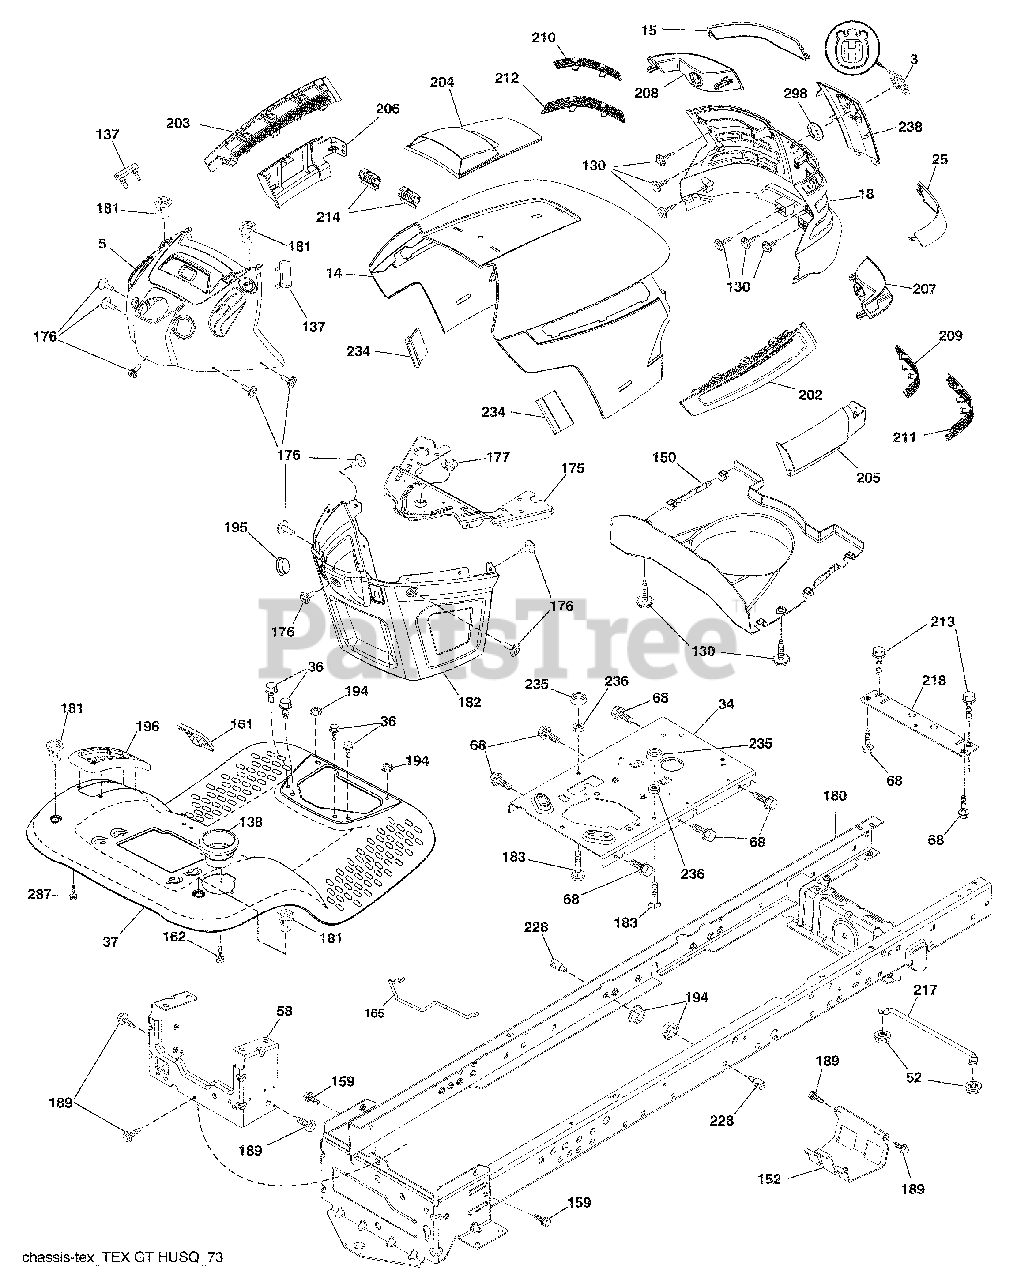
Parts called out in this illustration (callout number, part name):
3	Logo
14	Hood
18	Grille/Lens Asm.
34	Plate Engine
36	Screw 5/16-18 x 3/4
52	Nut Lock 5/16-18
58	Drawbar Upper 2PC Sml. Fender
68	Screw Thdrol 5/16-18 x 1/2
130	Screw #10 x 0.750
137	Bumper Dash
138	Cupholder
152	Shield Browning
159	Screw Hexwsh Thrd 3/8-16 x 3/4
161	Window Fuel
165	Support Tank
175	Crossmember
176	Screw 10-24 x 5/8
177	Bushing Steering
181	Bushing Mtg. Fender Crgo
182	Dash Lower
183	Bolt 5/16-18 x 1-1/4
189	Screw 5/16-18 x 3/4
194	Nut Lock Hex Flange 5/16-18
195	Plug Hole Dash Lower
196	Console Asm. Deck Lift
202	Vent Side Hood RH
203	Vent Side Hood LH
204	Vent Top Hood
205	Skirt Hood Side RH
206	Skirt Hood Side LH
209	Insert Hex Top RH
210	Insert Hex Top LH
211	Insert Hex Bottom RH
212	Insert Hex Bottom LH
213	Bolt 5/16-18 x 3/4
214	Clip Retainer Tinner
218	X-Piece Hood Stop
228	Stud Fastner
234	Bumper Hood
235	Spacer Fender
236	Nut Lock 5/16-18 unc
287	Screw 1/4-20 x 3/8
